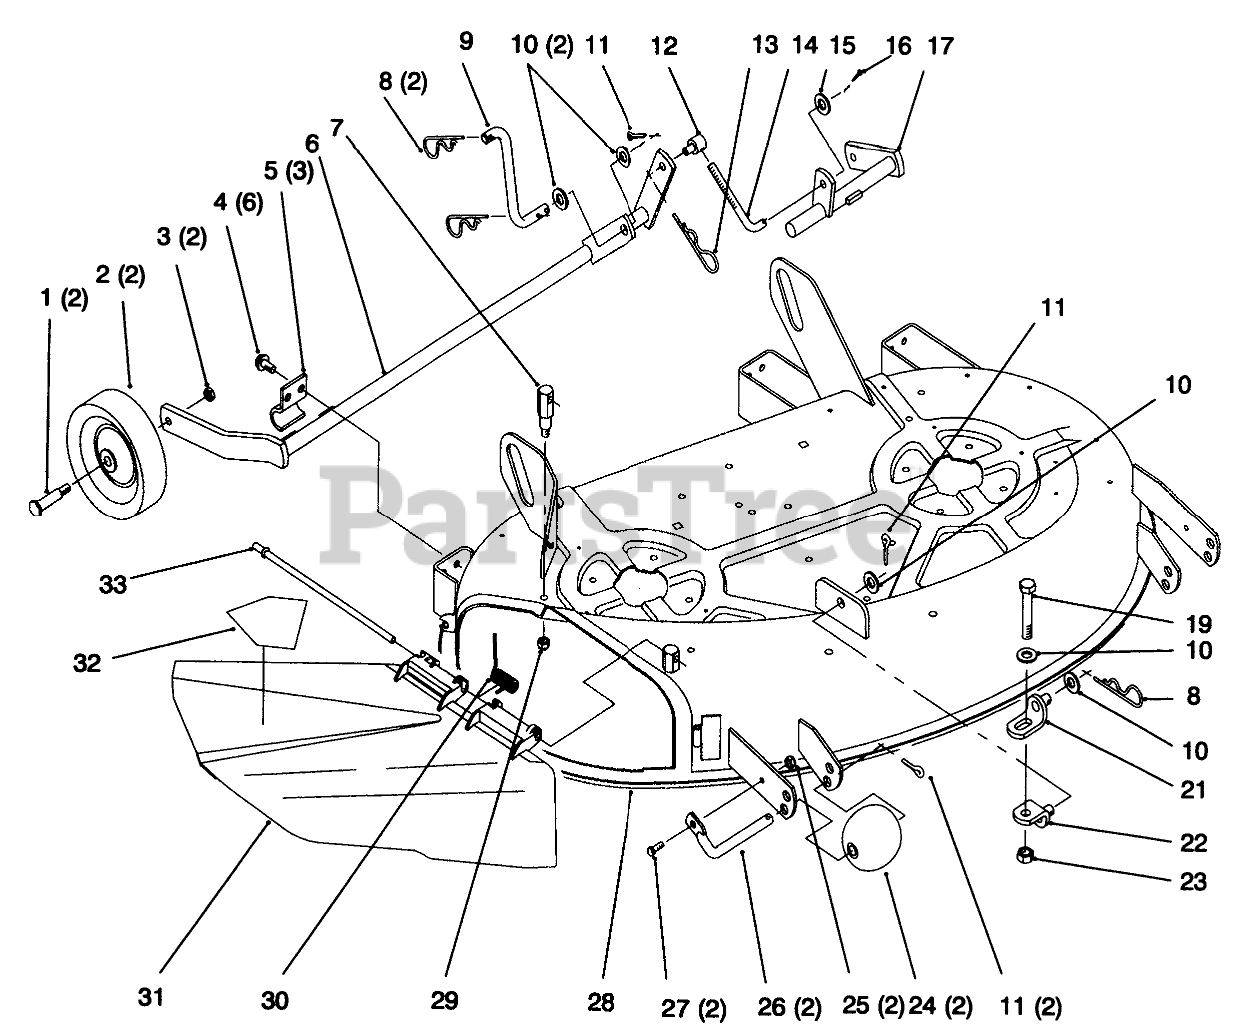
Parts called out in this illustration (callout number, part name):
1	BOLT-SHOULDER
2	WHEEL
3	NUT-HEX
4	SCREW-HWH, TAPTITE
6	SHAFT-RH
7	PIVOT POST - REAR
8	PIN-COTTER, HAIR
9	LINK-REAR
10	WASHER-FLAT
11	PIN-COTTER
12	TRUNNION
13	PIN-HAIR
14	ROD-LIFT
15	WASHER-FLAT
16	PIN-COTTER
17	SHAFT-LH
19	SCREW-HH
21	BRACKET-LIFT, LOWER
22	BRACKET-LIFT, UPPER
23	NUT-JAM
24	ROLLER
25	NUT-LOCK, NI
26	SHAFT-ROLLER
27	SCREW-HH
28	Asm-Decal
29	NUT-LOCK, NI
30	SPRING
31	DEFLECTOR ASM
32	DECAL-DANGER
33	ROD-HINGE DEFLECTOR
